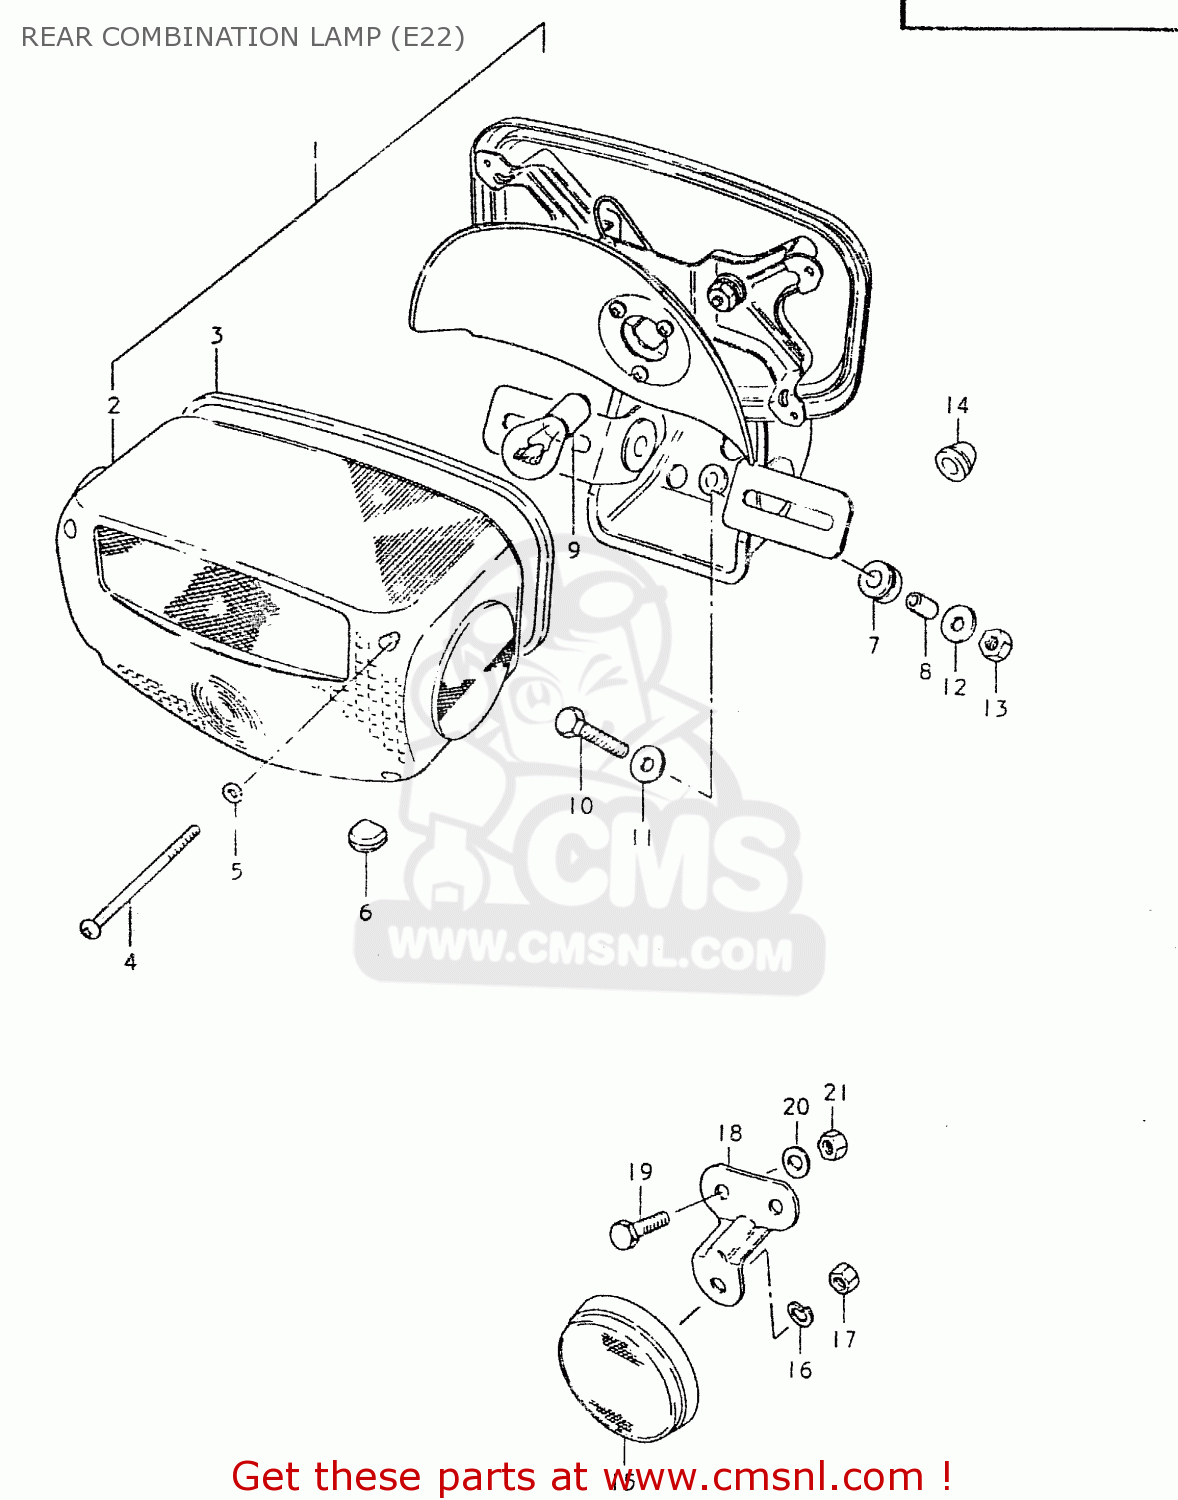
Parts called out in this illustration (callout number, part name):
1	LAMP ASSY, TAIL
2	LENS,RR COMBIN
3	GASKET (NAS)
4	SCREW (4X55)
5	GASKET (NAS)
6	GROMMET
7	CUSHION
8	SPACER
9	BULB(12V21/5W)
10	BOLT
11	WASHER (6.5X20X1.2)
12	WASHER
13	NUT
14	GROMMET
15	REFLEX REFLECTOR,RR
16	LOCK WASHER
17	NUT
18	BRACKET
19	BOLT
20	WASHER
21	NUT
